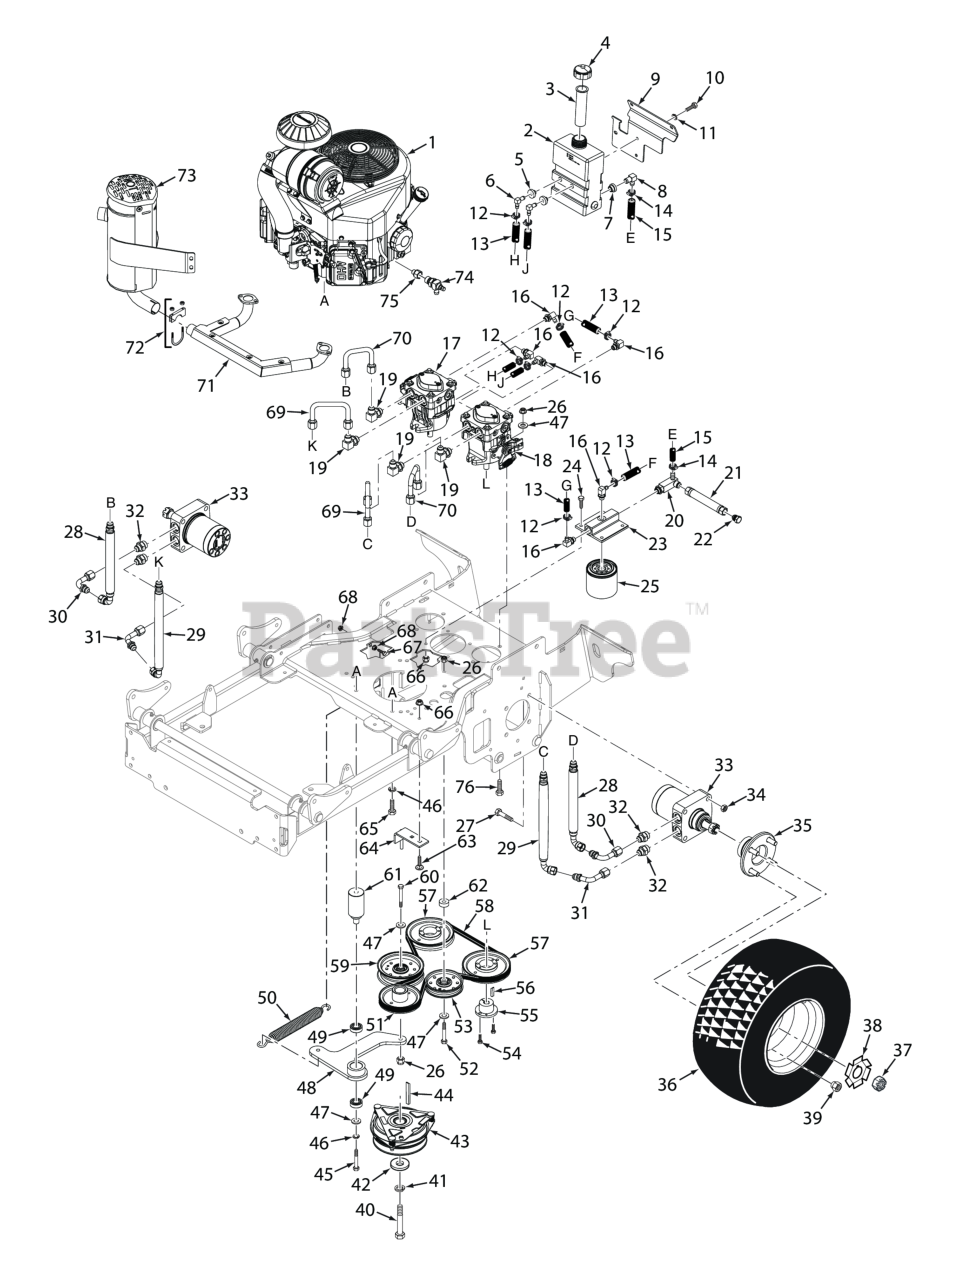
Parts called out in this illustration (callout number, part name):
1	Engine, 16 HP Kawasaki FX (32)
2	Hydro Tank Assy., SVRII
3	Insert, Filler Neck
4	CAP, HYDRAULIC TANK
5	Bushing, 0.56" Dia. Viton
6	Elbow, 90 Degree, 9/16-18 JIC x 9/16 O-Ring
7	Bushing, 0.78" Dia. Viton
8	Fitting, 90 Degree - 1/2" Hose
9	Bracket, Hydro Tank Mounting
10	BOLT, SERRATED FLANGE HEX HEAD 5/16-18 X 3/4"
11	Lockwasher, 5/16 (.317 x .586 x .078) Helical Spring
12	Clamp, .69" Max. / .25" Min. Dia.
13	Hose, 3/8" ID - 10-1/4" Long (Order By The Inch)
14	Clamp, Cable 3/4" I.D.
15	Hose Assembly, 1/2" ID (Oil Reservoir to Filter Base)
16	Elbow, 90 Degree - 9/16" O-Ring x 3/8" Hose
17	Pump, LH - 10cc (36 Only)
18	Pump, RH - 10cc (36 Only)
19	Elbow, 90 Degree 3/4-16 JIC x 3/4-16 O-Ring
20	Tee, 3/4" O-Ring
21	Drain Hose Assy.
22	Plug, JIC 3/4-16 UNF
23	Filter Head Assembly
24	BOLT, SERRATED FLANGE HEX HEAD 5/16-18 X 3/4"
25	OIL FILTER, SPECIAL
26	HEX NUT, ELASTIC STOP LOCK, 3/8-16
27	Bolt, Hex Hd. 1/2-13 x 2-1/2" (lower)
28	Hose Assy., 11-1/4"
29	Hose Assy., 13-1/4"
30	Tube Assy., 1/2 x 2 x 2"
31	Tube Assy., 1/2 x 2 x 3-1/4"
32	TUBE UNION, 3/4-16 JIC TO 7/8-14 "O" RING
33	Wheel Motor
34	Locknut, Hex 1/2-13 Center Lock
35	Wheel Hub Assembly (32)
36	Wheel Assy., 20 x 6.5 - 10 (32)
37	HEX CASTLE NUT, 3/4-28 UNEF
38	Lock Washer, Wheel Motor
39	Wheel Nut, 1/2-20 x 13/16
40	Bolt, Hex Head 7/16-20 x 2-1/4" w/Patch (Kawasaki)
41	Lockwasher, 7/16� Spring
42	Flatwasher, 7/16-.469 x 1.75 x .25 (48, 52)
43	Clutch w/Tag GT2.5-FE02 (48 / 52)
44	Key, 1/4 x 1/4 x 3-1/2"
45	Capscrew, Hex Head 3/8-16 x 3-3/4"
46	Lockwasher, 3/8" Spring, Kawasaki FX / FS
47	Flatwasher, 3/8 (.391 x .938 x .105 HD) Grade 8
48	Idler Arm Assy., Pump Drive
49	BEARINGS, BALL, NEUTRAL RETURN
50	Spring, Transmission Idler
51	Pulley, 4-3/4" OD - 1.125 Bore
52	Bolt, Hex Head 3/8-16 x 2-1/4" - 61"
53	Pulley, Idler 4� Dia.
54	Bolt, Hex Head 1/4-20 x 1" Grade 8 Black
55	Hub, Tapered, 15mm Bore
56	KEY, 5 MM X 5 MM X 25 MM
57	Pulley, 5.45 OD - Tapered Bore"
58	Belt, Pump Drive - SVRII-36
59	Pulley, 4" Dia. Idler
60	Bolt, Hex Head 3/8-16 x 2-1/4" - 61"
61	Pivot, Idler
62	Spacer, Idler Pulley - SFZ61
63	Bolt, 5/16-18 x .75 RHSN Carriage
64	ANTI-ROTATION WLMT, SVRII
65	Bolt, Hex Head 3/8-16 x 1-1/4", Kawasaki FX / FS
66	Nut, Serrated Flange 5/16-18 (Right Front Engine Mounting, Briggs and Kohler Only)
67	Bolt, Hex Head 3/8-16 x 1-1/2" Grade 8 Black
68	NUT, 3/8-16 SERRATED FLANGE HEX HEAD
69	1/2" U-Tube Assembly, 4" Wide
70	Tube Assy., 1/2 x 2" Wide
71	Exhaust Manifold, 16 HP Kawasaki FX
72	Muffler Clamp
73	Muffler, Kawasaki (FS481, FS541, FS600)
74	Oil Drain, 35BV & 37BV-EFI - Briggs & Stratton
75	FITTING, M14 FEMALE TO M20 MALE
76	Bolt, Hex Head, 3/8-16 x 1-1/2"
